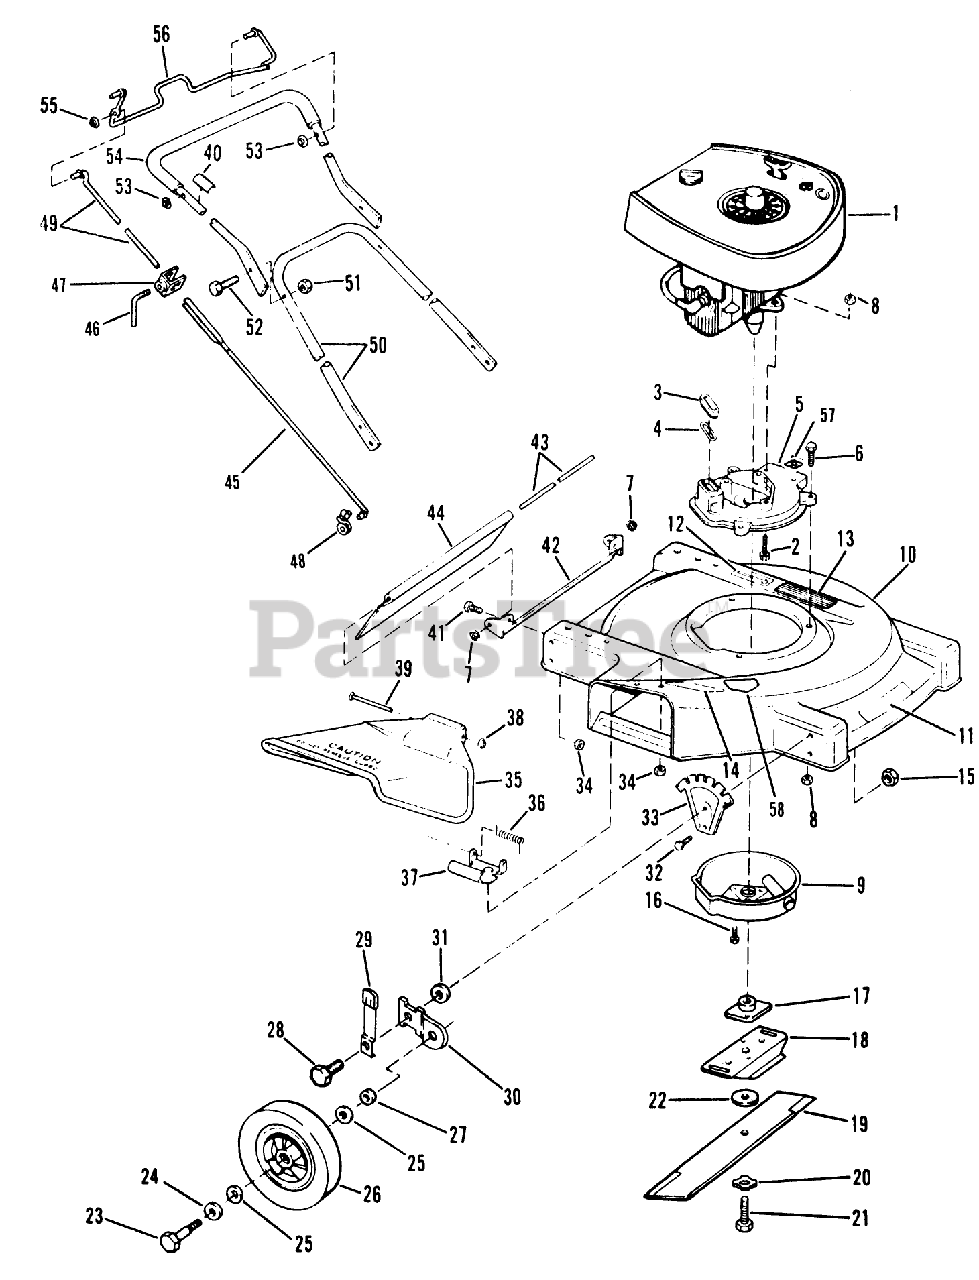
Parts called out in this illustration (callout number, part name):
4	GASKET S
8	NUT-LOCK F
13	PAD FOOT
15	LOCKNUT
20	LOCKWASHER
21	BLADE BOLT
23	BOLT WHEEL
27	WASHER WROUGHT
29	KNOB&SPRING FORMCO
34	LOCKNUT E
35	CHUTE DEFLECTOR AY
37	HINGE & SCREW ATA
42	BRACKET (12)
44	TRAILING SHIELD
51	LOCKNUT E
52	SCREW - USE 137-3042
